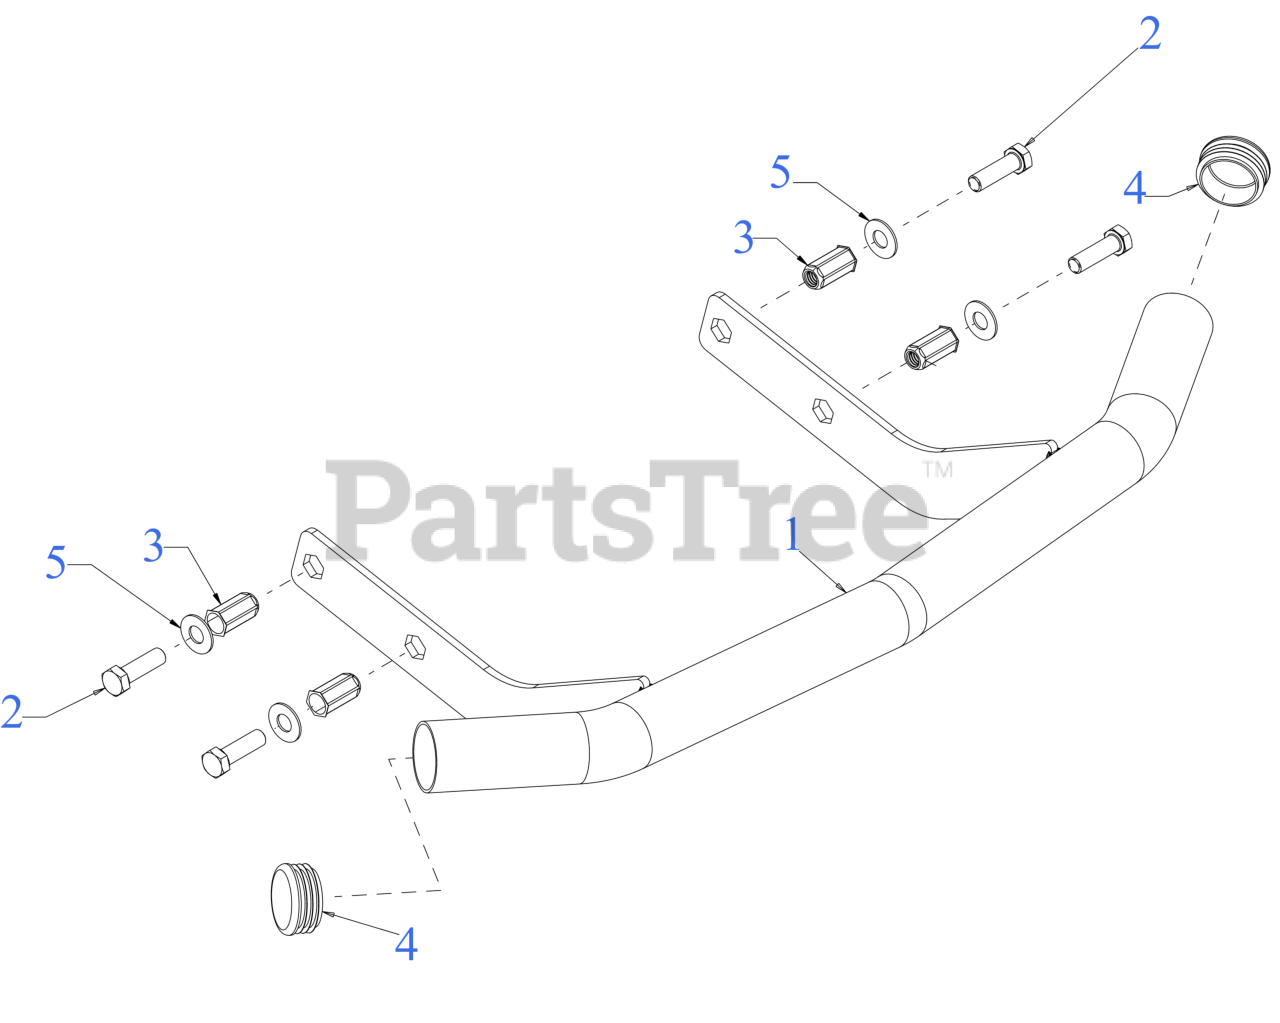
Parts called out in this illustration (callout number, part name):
1	BUMPER ASSEMBLY (RED)
2	SCREW 3/8-16 x 1.25 GR5
3	NUT RIVET 3/8-16
4	BUMPER CAP
5	FLAT WASHER .401X.88
